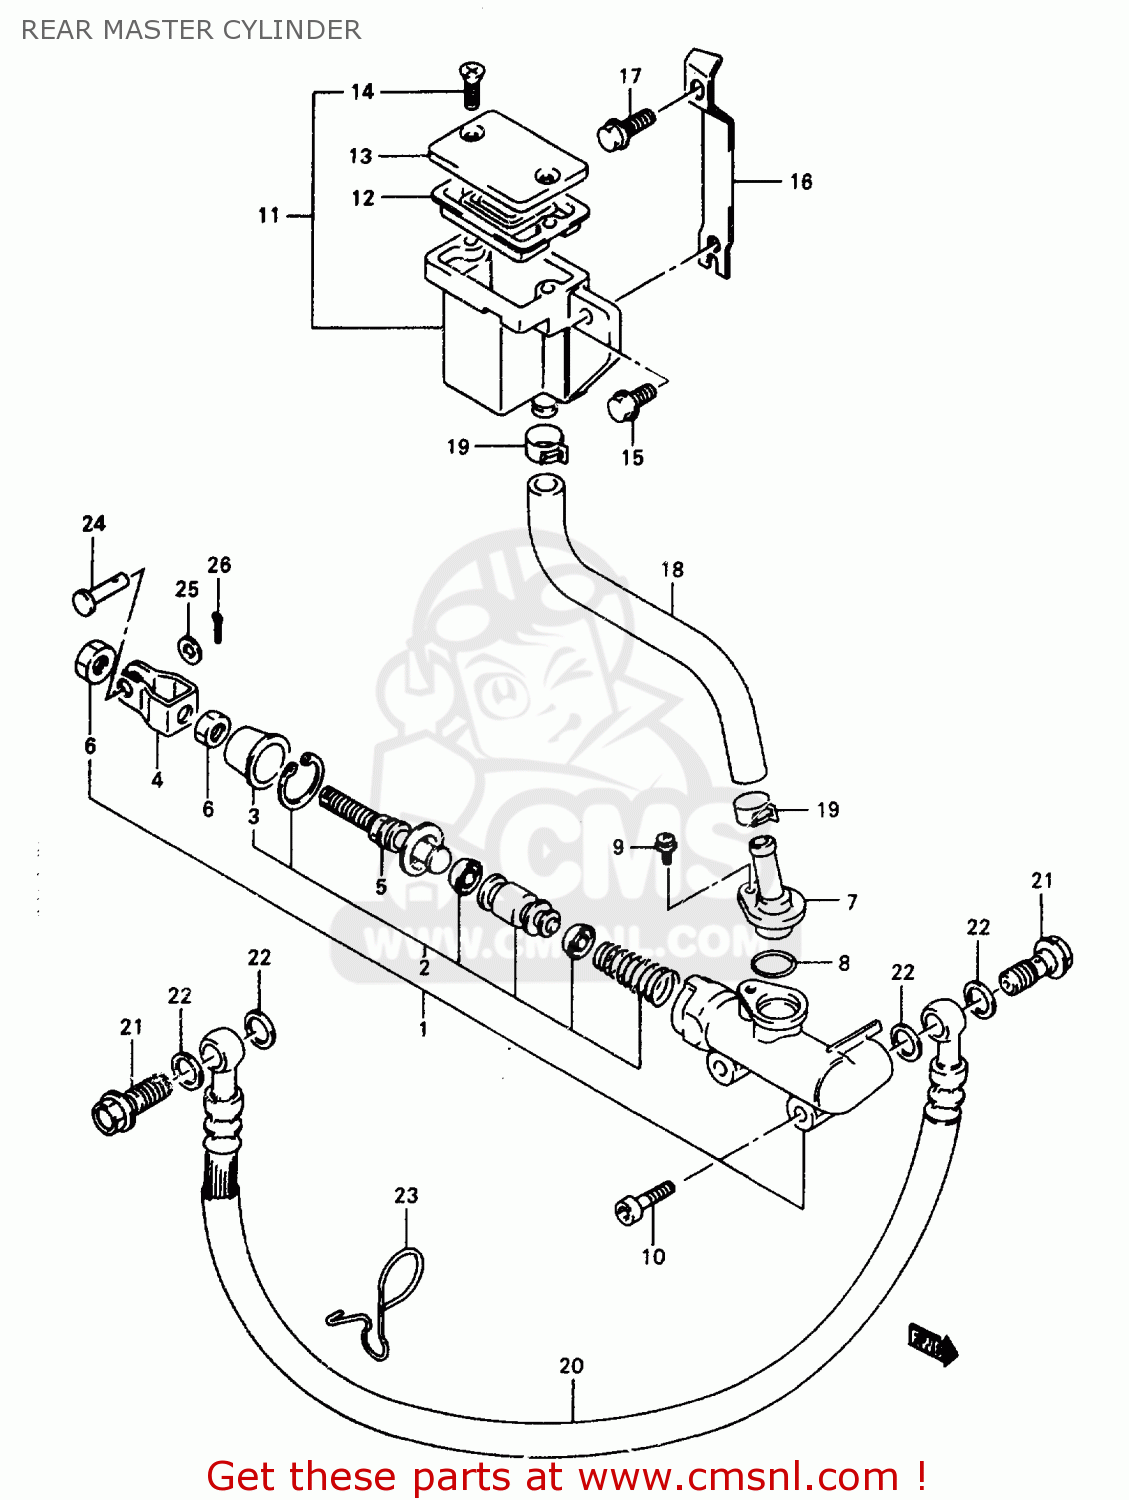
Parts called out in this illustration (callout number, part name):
1	CYLINDER ASSEMBLY,REAR MASTER
2	PISTON/CUP SET
3	BOOT
4	YOKE
5	ROD,PUSH
6	NUT
7	CONNECTOR
8	O RING
9	SCREW
10	BOLT,OIL FILLE
11	TANK ASSY,RESERVOIR
12	DIAPHRAGM
13	CAP
14	SCREW
15	BOLT
16	PLATE,RESERVOIR TANK
17	BOLT
18	HOSE,RESERVOIR TANK
19	CLIP
20	HOSE,RR BRAKE
21	BOLT UNION
22	WASHER(10X15X1.5)
23	GUIDE,BRAKE HOSE
24	PIN
25	WASHER
26	PIN
